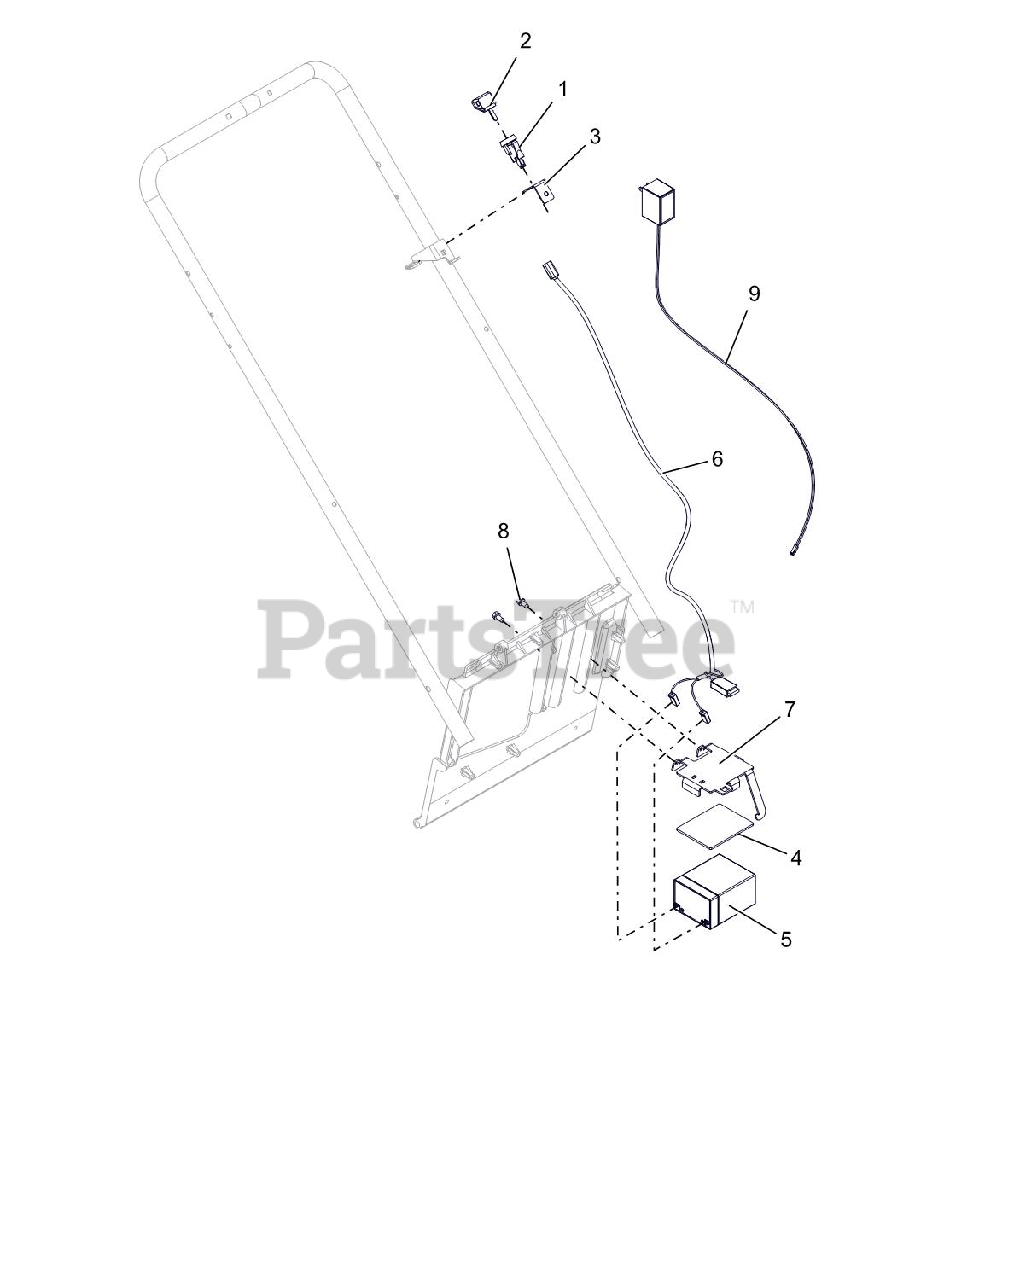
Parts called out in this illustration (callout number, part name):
1	SWITCH, KEY
2	KEYS, IGNITION
3	BRKT, KEY SWITCH
4	PAD, BATTERY, LM
5	BATTERY, AGM, 2.9AH, GNRL PRPS
6	HARNESS, ELEC START
7	BRKT, BATTERY HOLD DOWN
8	SCR-TAP .25-20X.50 HWH TR YWZ
9	CHARGER, BATTERY
